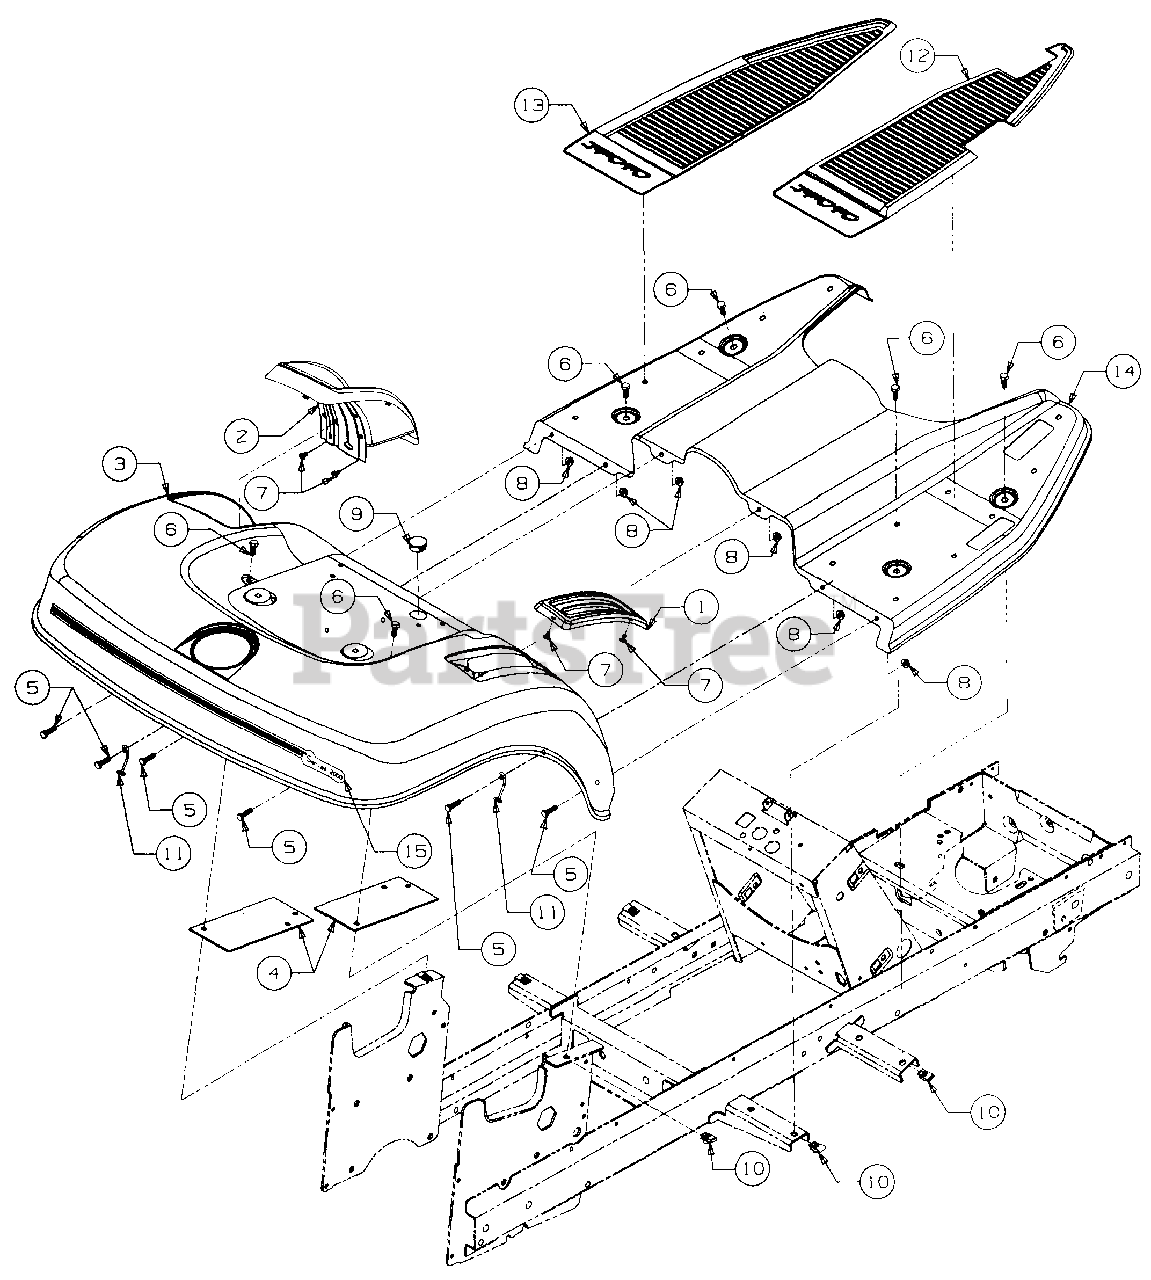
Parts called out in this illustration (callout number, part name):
1	Cover, 6-Speed Shifter
2	Cover, Implement Lift
4	Plate, Fender Reinforcement
5	Screw, Hex Cap, 1/4-20 x .62 Lg
6	Screw, Hex Wash Sf Tapp, 5/16-18 x .75 Lg
7	Screw, Hex Tapp, #10 x .38 Lg
8	Nut, Hex Flange Lock, 1/4-20
9	Bushing, Snap, 7/8 ID
10	U-Nut, 5/16-18
11	Retainer, Hook
12	Pad, RH Foot
13	Pad, LH Foot
15	Graphic, Rear Fender
